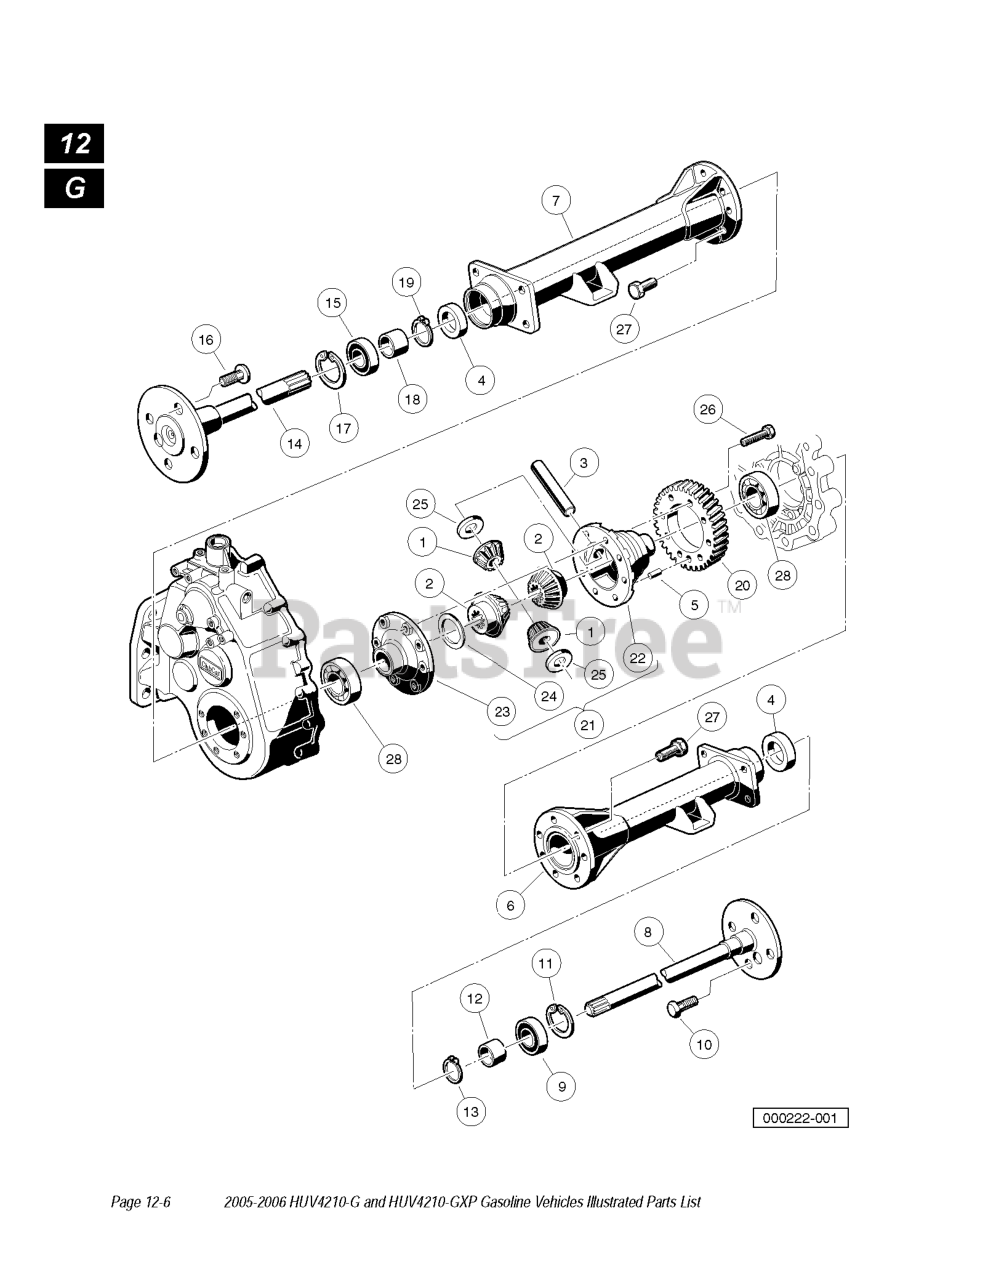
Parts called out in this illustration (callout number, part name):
1	DIFFERENTIAL IDLER GEAR
2	DIFFERENTIAL GEAR
3	DIFFERENTIAL PIN
4	AXLE SHAFT OIL SEAL
6	PIPE - COMP.
7	PIPE - COMP.
8	AXLE ASSEMBLY
9	OUTER AXLE, TUBE BEARING
11	CIRCLIP TYPE C
12	BUSHING W/25 MM I.D.
13	RETAINING RING
14	AXLE ASSEMBLY
15	OUTER AXLE, TUBE BEARING
17	CIRCLIP TYPE C
18	BUSHING W/25 MM I.D.
19	RETAINING RING
20	GEAR HELICAL
21	DIFF. GEAR CASE KIT
22	DIFFERENTIAL GEAR CASE L.H.
23	DIFFERENTIAL GEAR CASE R.H.
24	PLATE, THRUST (DIFF. GEAR)
25	PLATE
26	SCREW, M8-1.25 X 35MM HEX HEAD
27	BOLT, M10 X 1.5 X 30MM
28	INNER AXLE, TUBE BEARING
